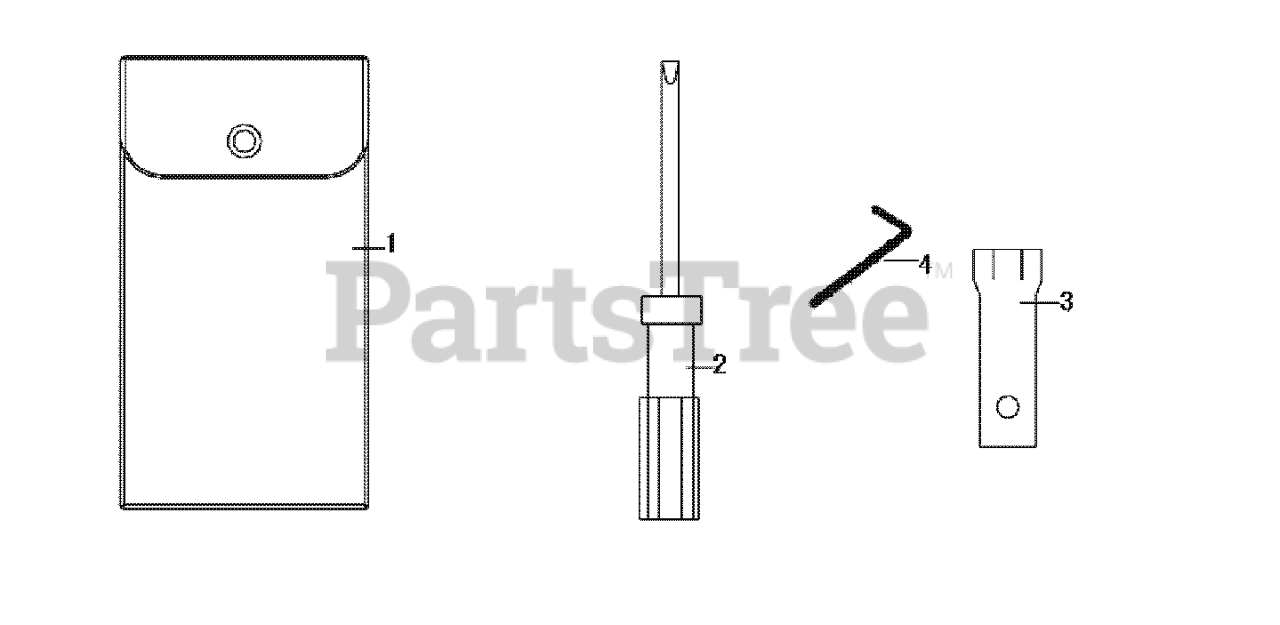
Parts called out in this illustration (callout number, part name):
1	BAG, TOOLS
2	SCREW DRIVER
3	SOCKET, SPARK PLUG
4	ALLEN WRENCH
